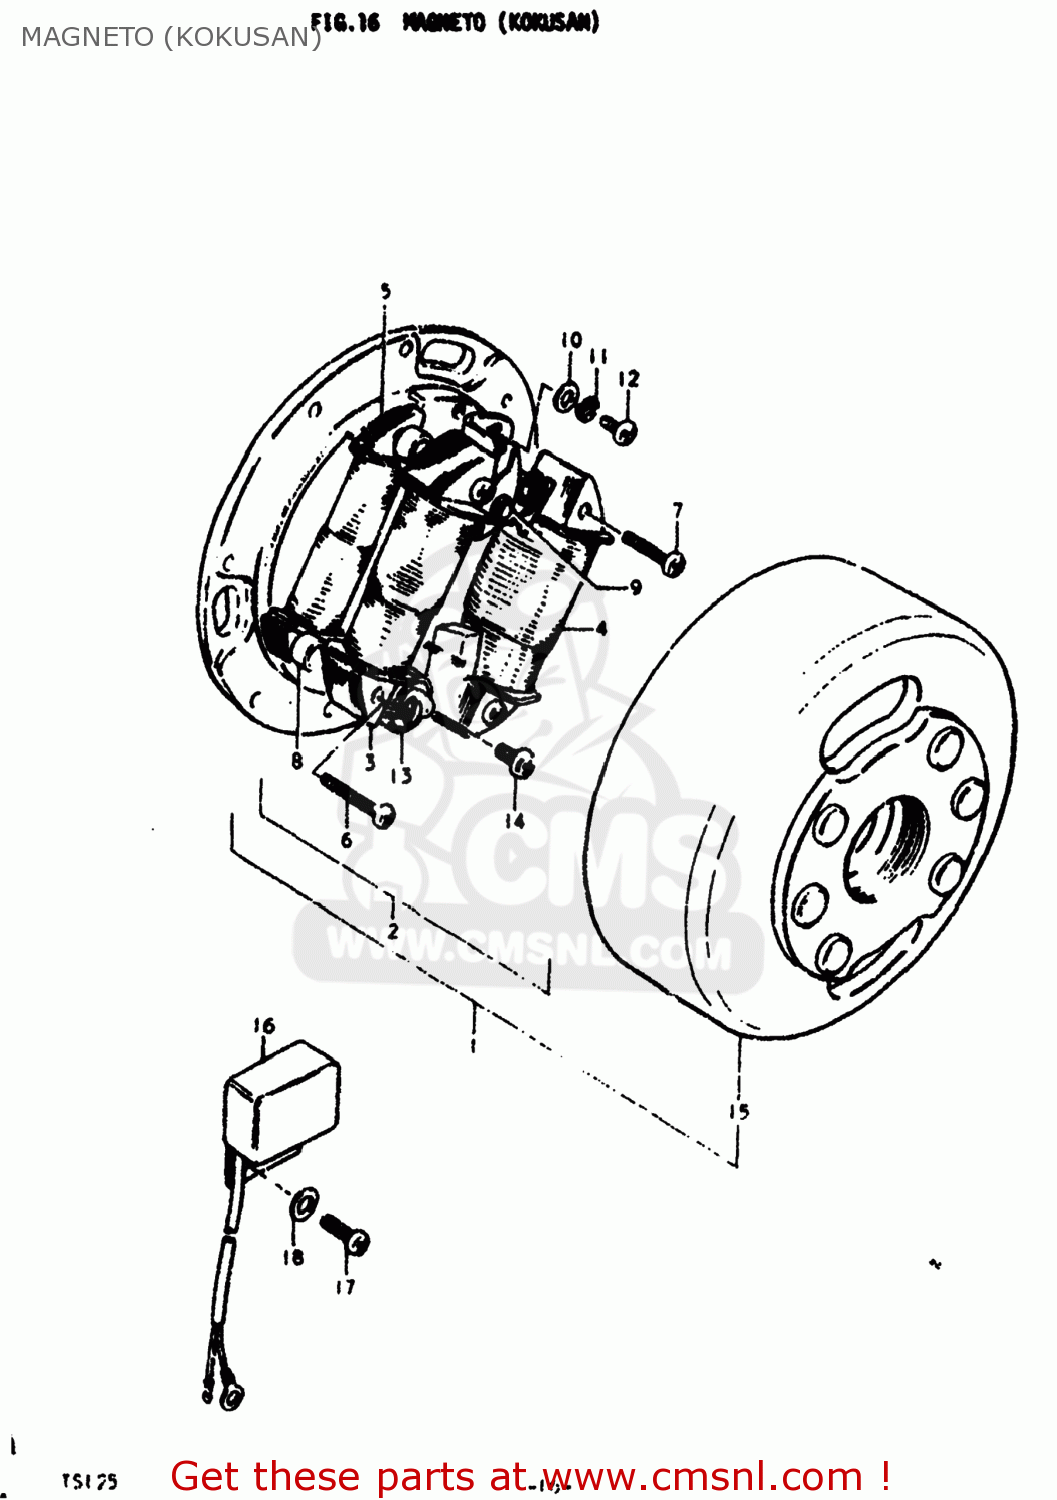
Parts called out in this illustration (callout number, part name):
1	MAGNETO ASSEMBLY
2	STATOR ASSEMBLY
3	COIL,PRIMARY
4	COIL,LIGHTING
5	COIL
6	SCREW
7	SCREW 4X25
9	POINT ASSY,CONTACT
10	WASHER
11	LOCK WASHER
12	SCREW(4X10)
13	CONDENSER
14	SCREW
15	ROTOR ASSEMBLY
16	REGULATOR ASSEMBLY
17	SCREW 6X12
18	WASHER
